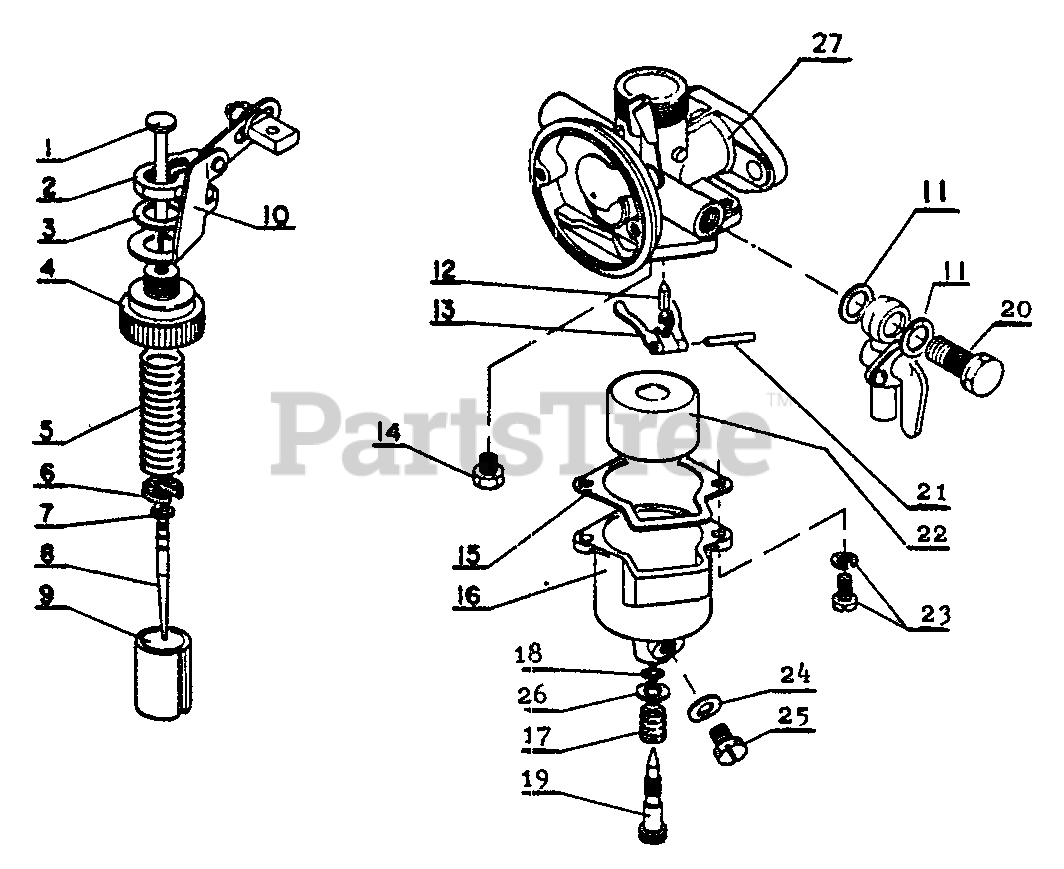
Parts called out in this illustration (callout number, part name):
1	BAR, LINK
2	NUT
3	WASHER
4	COVER - TOP
5	SPRING, THROTTLE
6	SEAT, SPRING
7	RING, RETAINING
8	NEEDLE, JET
9	VALVE, THROTTLE
10	LEVEL ASSY
12	VALVE, INLET NEEDLE
13	LEVER, METERING
14	JET, MAIN
15	GASKET, FLOAT CHAMBER
16	CHAMBER, FLOAT
17	SPRING, METERING LEVER
18	O-RING
19	NEEDLE, METERING
20	BOLT, BANJO
21	PIN, METERING LEVER
22	FLOAT
23	SCREW - 4X14
24	GASKET, DRAIN
25	SCREW - 4X6
26	WASHER
27	BODY, CARBURETOR
